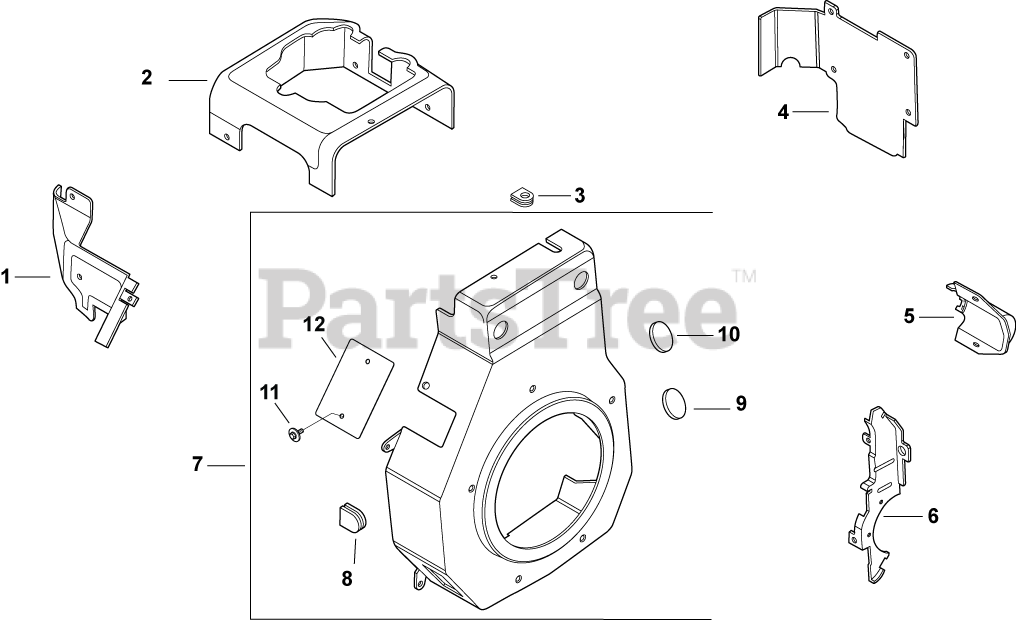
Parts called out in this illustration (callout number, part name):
1	BAFFLE, INTAKE SIDE
2	BAFFLE, CYLINDER
4	BAFFLE, CYLINDER HEAD
5	COVER, STARTER
6	PLATE, BACKING
7	KIT, BLOWER HOUSING
9	PLUG, BUTTON 1/2
10	PLUG, BUTTON 9/16
11	SCREW, SEMS DRILL #8-18X1/2"
12	PLATE, COVER
